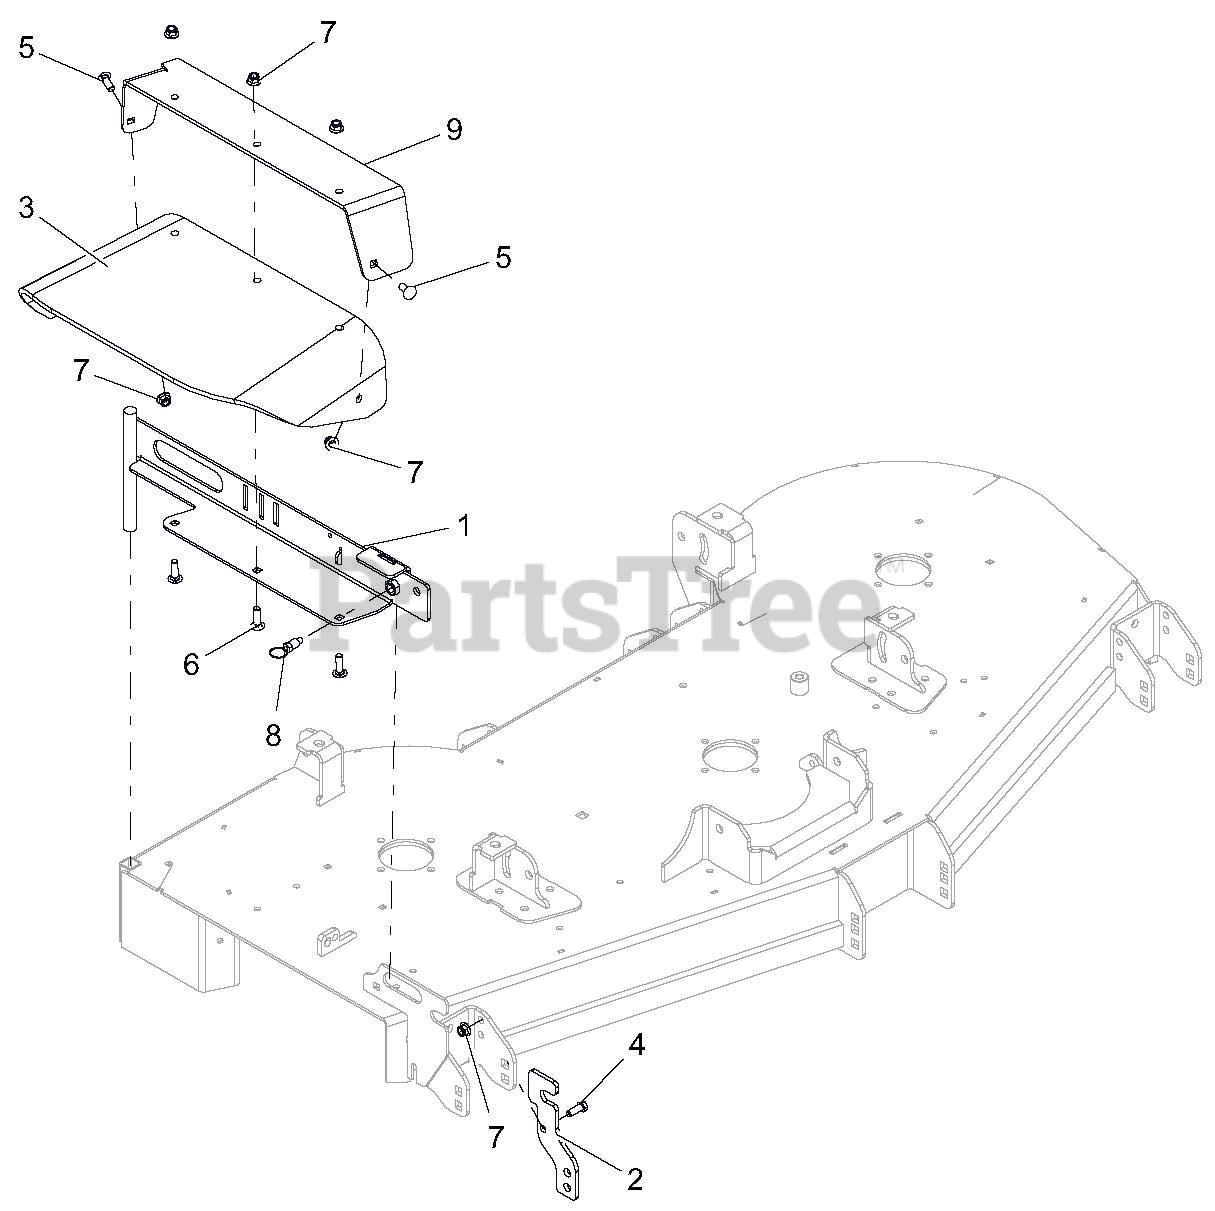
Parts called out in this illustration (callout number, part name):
1	WLDMT, 52"-60" DISCH CHUTE MTG
2	CHUTE STORAGE BRACKET
3	CHUTE, RUBBER DISCHARGE
4	BLT-HEX .38-16X1.00 GR5 YWZC
5	BLT-RDHDSQNK .38-16X1.00 G5 YWZC
6	BLT-RDHDSQNK .38-16X1.25 G5 YWZC
7	NUT-LK-NYL-FLG .38-16 YWZC
8	PULL PIN,.50-13THDX.310 PLNGR
9	DISCHARGE CHUTE SUPPORT W/SAFETY DECAL
